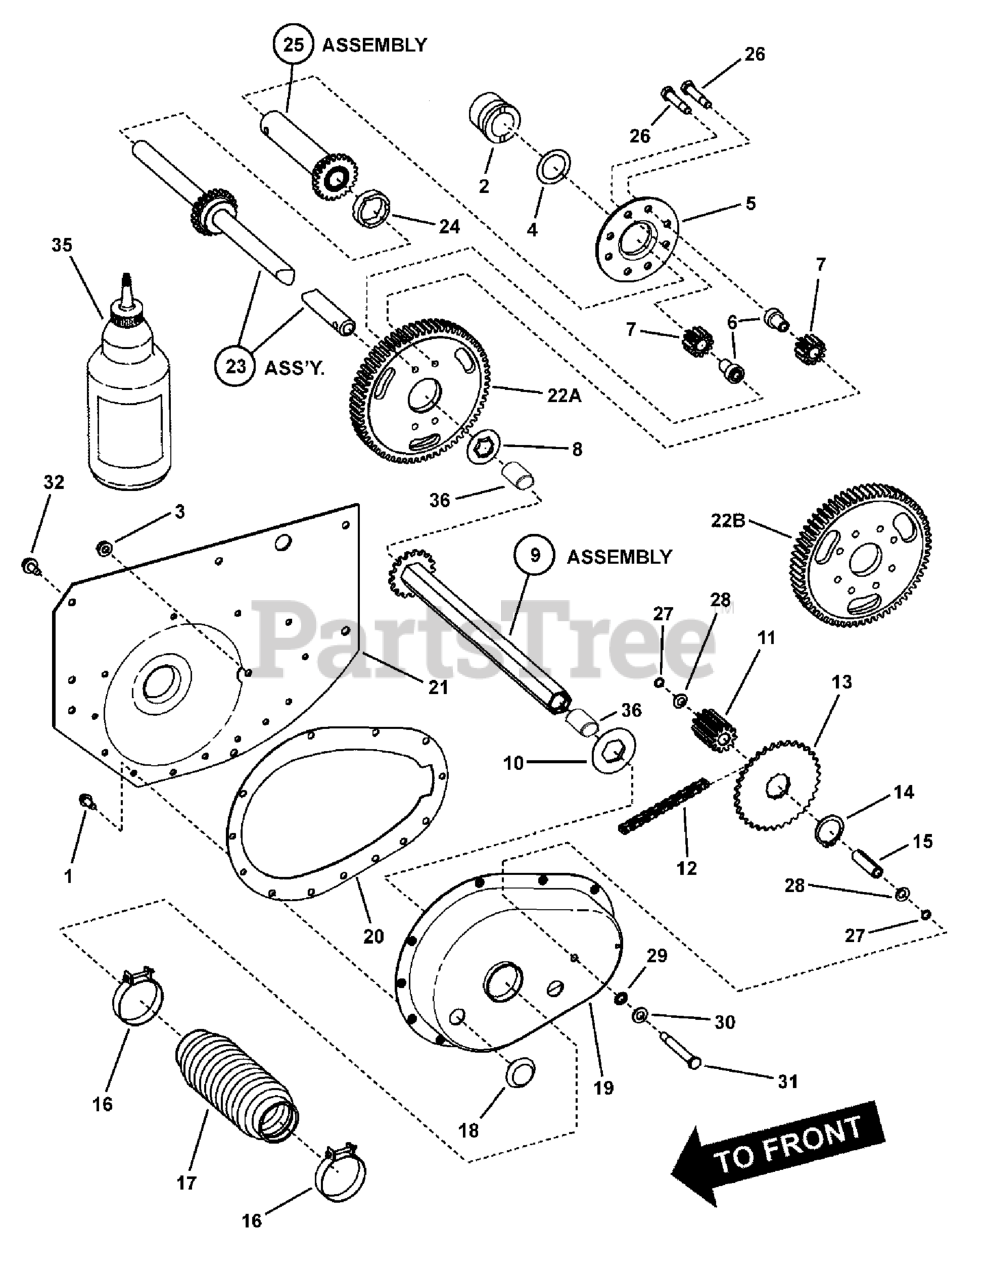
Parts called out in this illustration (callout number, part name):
1	SCREW, 1/4-20 x 5/8" Hex Washer Head Self-Tap
2	BEARING, Axle (R. H. Fender)
2	BEARING-DX, Axle (R. H. Fender)
3	NUT, 5/16-24 Flange Lock (Large)
4	WASHER, Thrust
5	PLATE, Differential
6	SPACER, Pinion
7	GEAR, Differential Pinion (12T 12P)
8	WASHER, Thrust
9	ASSEMBLY, Drive Hex Tube
10	WASHER, Nylon
11	GEAR, 11 Tooth, 10 Pitch
12	CHAIN, 46 Pitch (#35 Endless)
13	SPROCKET, 34T, 3/8P
14	RING, 1-3/16" External Retaining
15	SPACER, Differential Case
16	BOOT CLAMP, 2"
17	BOOT, Oil Seal (Short Axle)
18	PLUG, 1/2" Cup Insert
19	CASE, Transmission
20	GASKET, Transmission Case
21	FENDER, Right Hand (1.62" Dia. Hole)
22A	GEAR, 63 Tooth 10 Pitch (4 Hole)
22B	GEAR, 63 Tooth 10 Pitch (8 Hole)
23	KIT, Long Axle Structure
24	SPACER, Differential Case
25	ASSEMBLY, Short Axle, 23T (Includes Gear)
26	BOLT, 5/16-24 x 1-5/8" Hex Special Lock (Vibresist)
27	5/16" O-RING
28	WASHER, 5/16" Belleville
29	WASHER, 5/16" External Tooth Lock
30	WASHER, .34 x .69 x .08 Flat
31	SCREW, 5/16-24 x 2-5/8" Hex Head Cap
32	SCREW, 5/16-18 x 5/8" Hex Washer Self-Tap
35	GREASE, Transmission (24 oz. Required)
36	BEARING, DX
